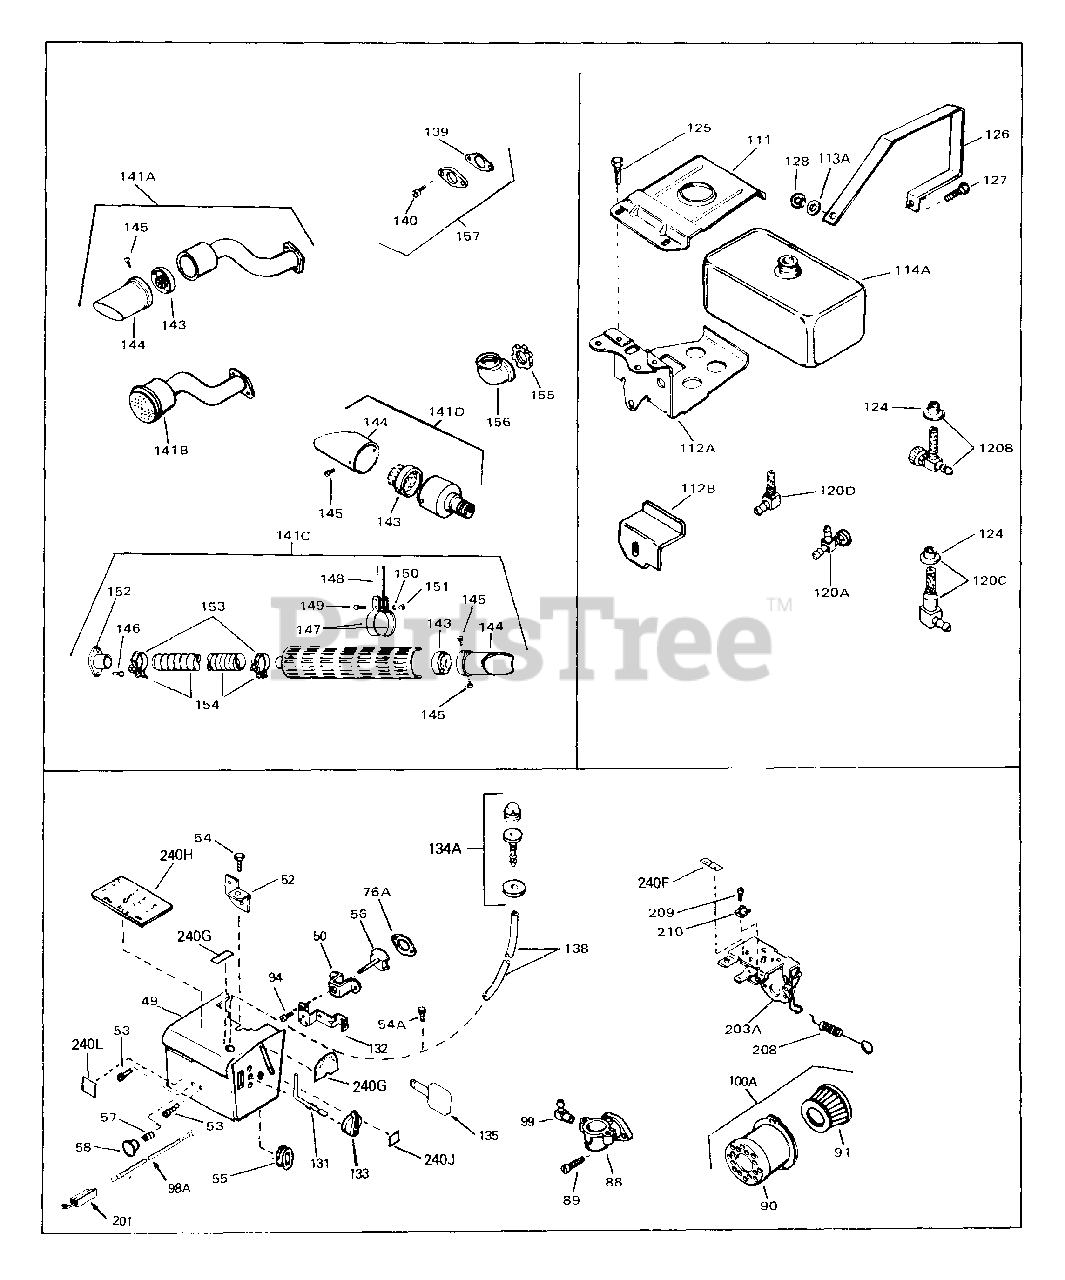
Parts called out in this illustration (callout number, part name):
49	Cover, Carburetor
50	Bracket, Coke
52	Bracket, Carburetor cover
53	Screw, Pan hd. Sems, 8-32 x 5/16
54	Screw, Hex hd. Sems taptite, 10-24 x 3/8
55	Grommet, Carburetor cover
94	Screw, Fil. hd. Sems, 10-32 x 1/2
100A	Cleaner Assy., Air (Paper)
113A	Washer, Flat
134A	Primer Assy.
138	Line, Primer
139	Gasket, Muffler
140	Screw, Fil. hd. Sems, 1/4-20 x 112
140	Screw, Fil. hd. Sems, 1/4-20 x 2-1/2
141D	Muffler
157	Muffler, Adapter Kit
201	Terminal Assy.
203A	Bracket, Control
208	Control, Choke
240G	Decal, Primer
240J	Decal, Warning
